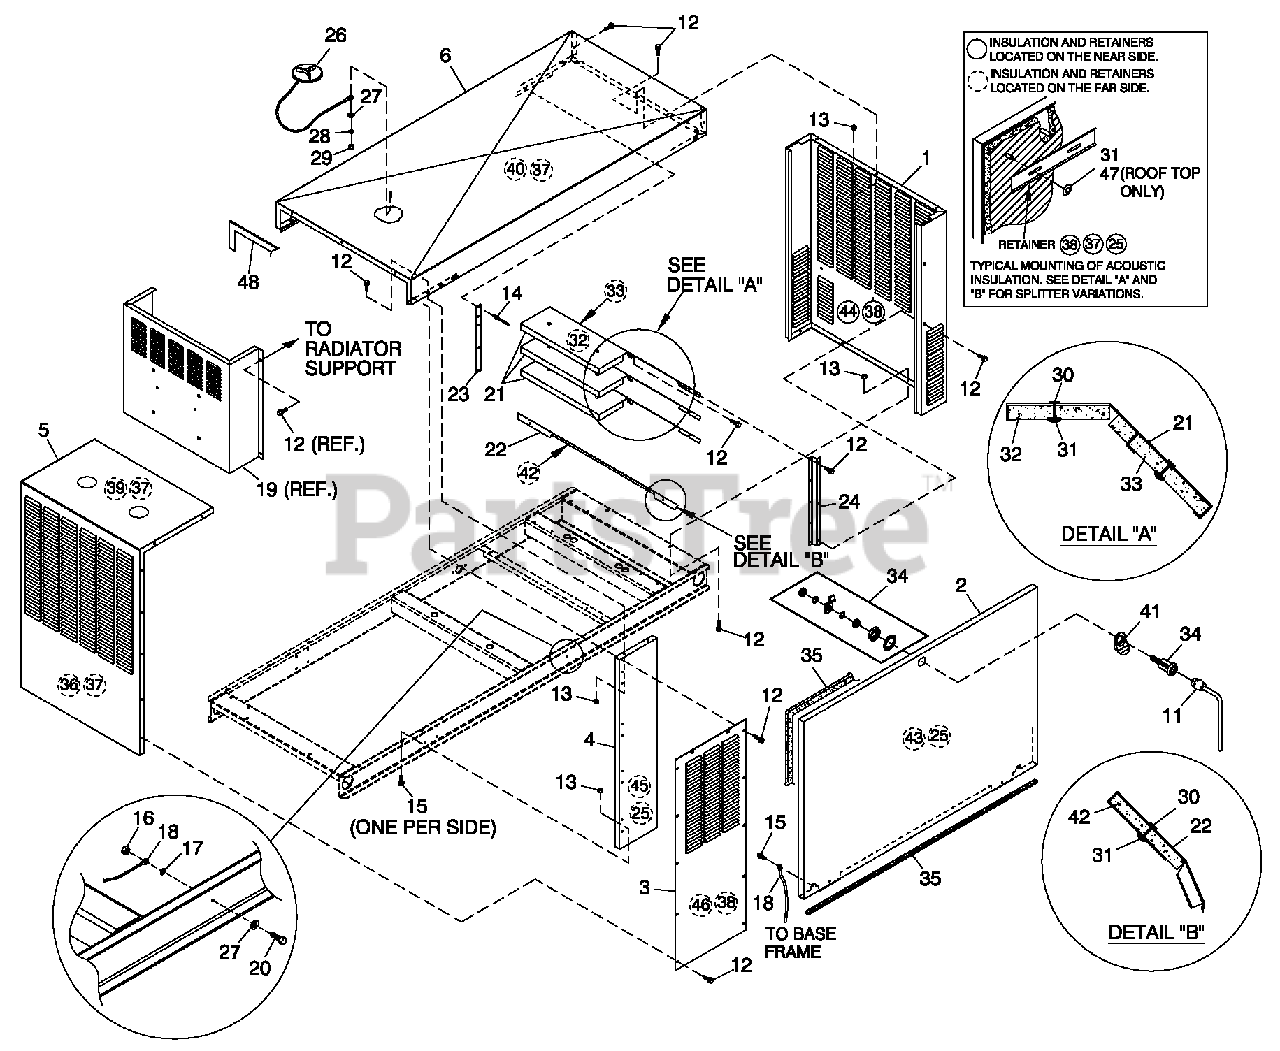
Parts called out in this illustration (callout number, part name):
1	REAR WRAP C4
2	DOOR C4
3	DISCHARGE DUCT LH & RH SIDE C4
4	FRONT CORNERS C4
5	DISCHARGE CENTER DUCT C4
6	ROOF C4ALU M
11	KEY VISE-ACTION LATCH SLOT CIR
12	SCREW THF M6-1 X 16 N WA Z/JS
13	NUT HEX LOCK M6-1.0 SS NY INS
14	RIVET POP .1875 X .450 SS
15	SCREW HWHTF M6-1.0X16
16	NUT HEXM6X1.0G8YEL CHR
17	WASHER SHAKEPROOF INT 1/4
18	ASSY WIRE 14AWG 34.8" GRN/YEL
19	INNER DISCHARGE DUCT, C4
20	SCREW HHC M6-1.0X20G8.8
21	SPLITTER C4
22	SPLITTER LOWER C4
23	STRINGER SPLITTER C3
24	SUPPORT SLITTER C4
25	RETAINER INSULATION (820)
26	ASSE MBLY COVER ACCESS
27	WASHER FLAT 1/4- M6ZINC
28	WASHER LOCK M6-1/4
29	NUT HEX 1/4-20 STEEL
30	INSULATION RETAIN MENT HANGER
31	WASHER SELF LOCKING DO ME #4-40
32	INSULATION SPLITTER
33	INSULATION LOWER SPLITTER
34	VISE-ACTION LATCH SLOTTED CIR
35	GASKET EXTRUDED TRI M (374.64" LG)
36	INSULATION DISCHARGE FRONT
37	RETAINER INSULATION (740)
38	RETAINER INSULATION (450)
39	INSULATION DISCHARGE TOP
40	INSULATION ROOFTOP
41	TAB PULL
42	INSULATION LOWER SPLITTER
43	INSULATION DOOR
44	INSULATION REAR WRAP
45	INSULATION CORNER POST
46	INSULATION DISCHARGE SIDE
47	WASHER SELF LOCKING DO ME #8-32
48	STRIP SEALANT 1/8 X 1 (44.52"LG)
